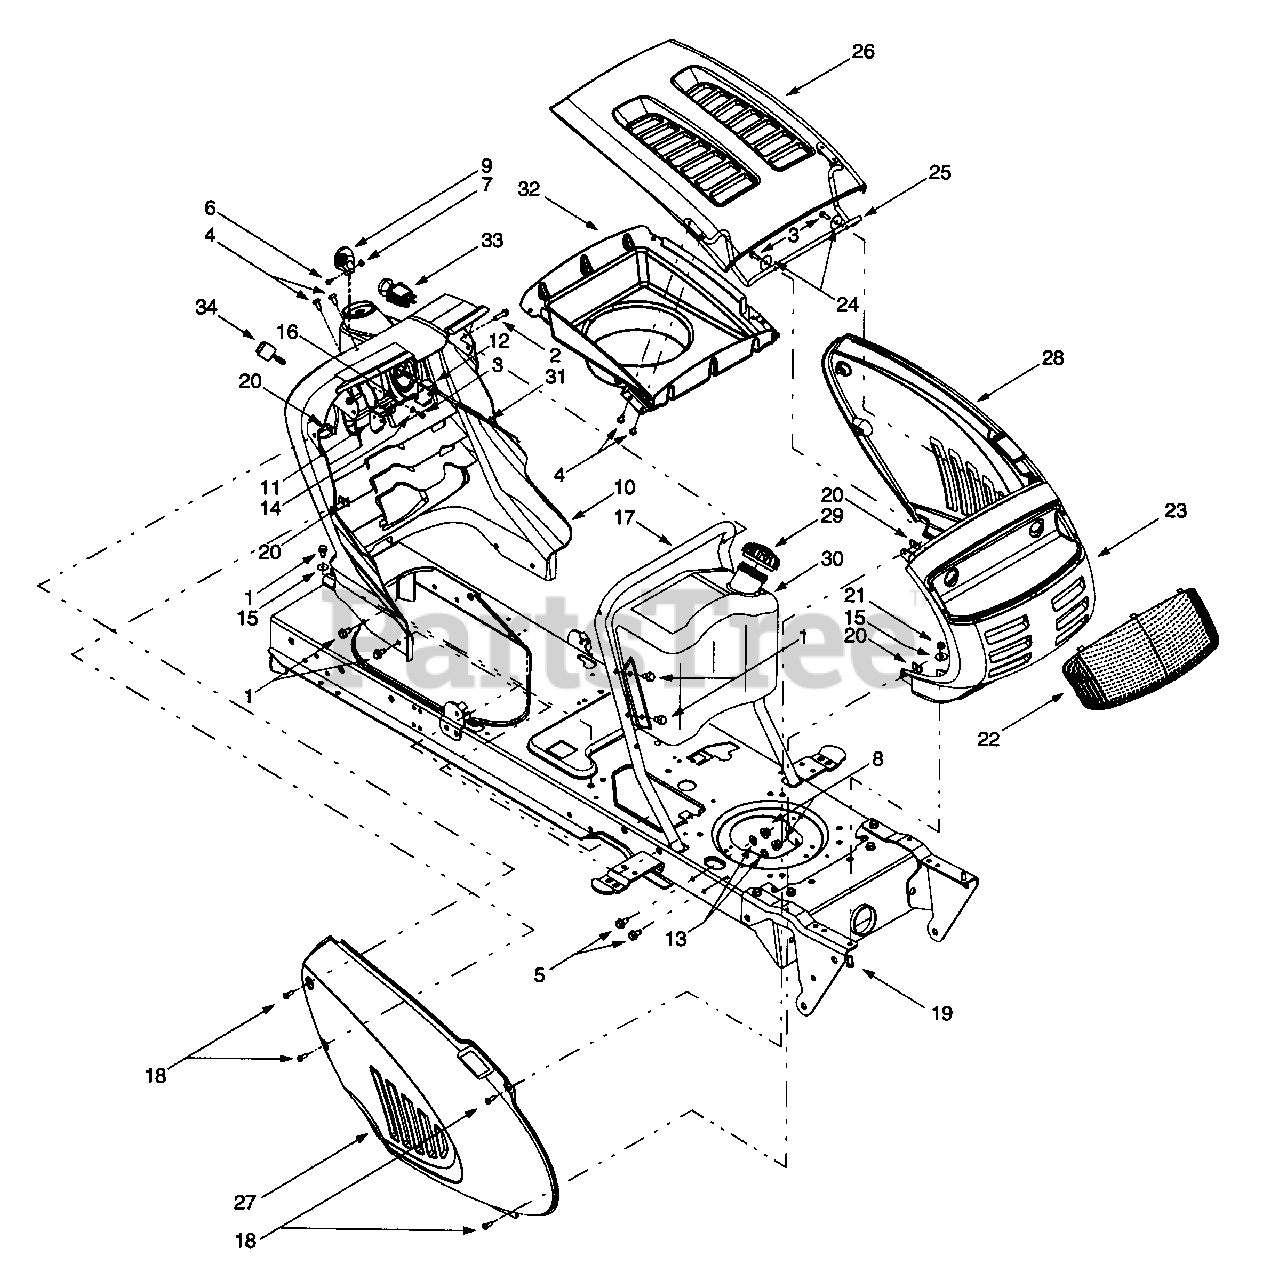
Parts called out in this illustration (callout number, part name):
1	Self Tapping Screw, 5/16-18 x .625
2	Self Tapping Screw, 1/4-20 x 1.0
3	Self Tapping Screw, 1/4-15 x .75
4	Torx Self Tapping Screw, 5/16-18 x .625
5	Screw, 5/16-18 x .875 (Grade 5)
6	Torx Screw, #8-32 x .375
7	Hex Nut, 8-32
8	Hex Nut, 5/16-18
9	Throttle Control Lever
10	Dash Panel (9-style)
11	Cruise Control Button
12	Parking Brake Button
13	Lock Washer, 5/16
14	Flat Washer, .281 x .5 x .063
15	Flat Washer, .349 x 1.0 x .063
16	Brake/Cruise Pivot Rod
19	Hex Cap Screw, 5/16-18 x .75
20	U-type Speed Nut, 1/4-20
21	Flange Lock Nut, 5/16-18
22	Lens (9-style)
23	Grille (9-style)
24	Flat Washer, .285 x 1.25 x .08
25	Hood Hinge Rod
30	Fuel Tank (two gallon)
31	Choke Knob/Cable Assembly
32	Hood Plenum
33	Electric PTO Switch
34	Ignition Key
